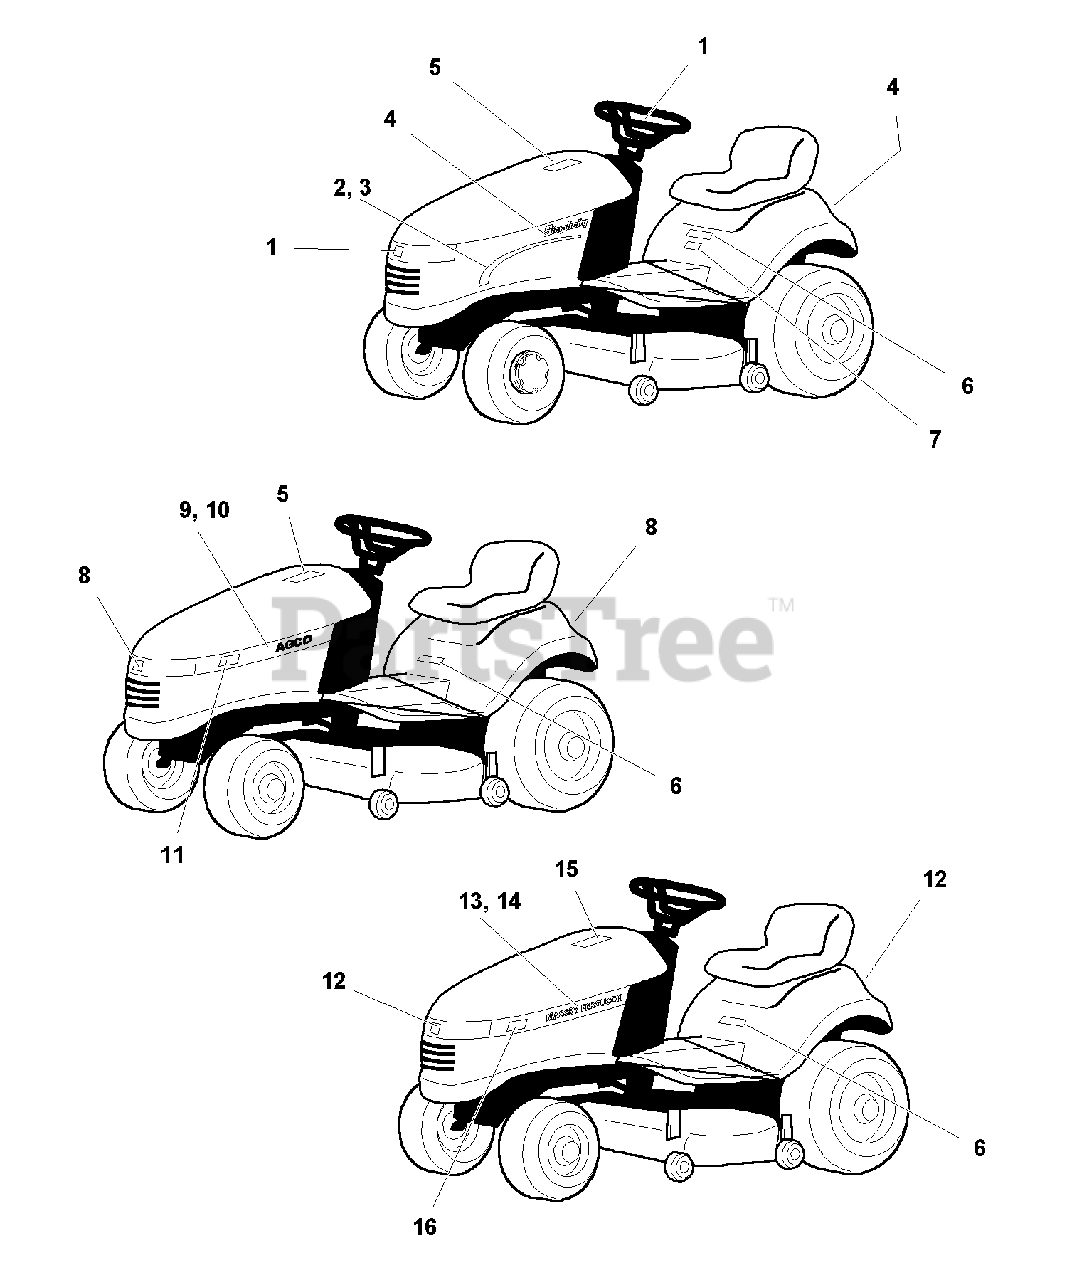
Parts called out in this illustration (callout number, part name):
1	DECAL, Simplicity Icon
2	DECAL, Simplicity Stripe RH
3	DECAL, Simplicity Stripe LH
4	DECAL, Simplicity
5	DECAL, Touch Up Paint
6	DECAL, Silver & Blue
7	DECAL, 15HP
8	DECAL, AGCO Logo
9	DECAL, AGCO, Hood RH Stripe
10	DECAL, AGCO, Hood LH Stripe
12	DECAL, Massey Ferguson
13	DECAL, Massey Ferguson Hood RH
14	DECAL, Massey Ferguson Hood LH
15	DECAL, Touch Up Paint, Massey Ferguson
16	DECAL, 2515
